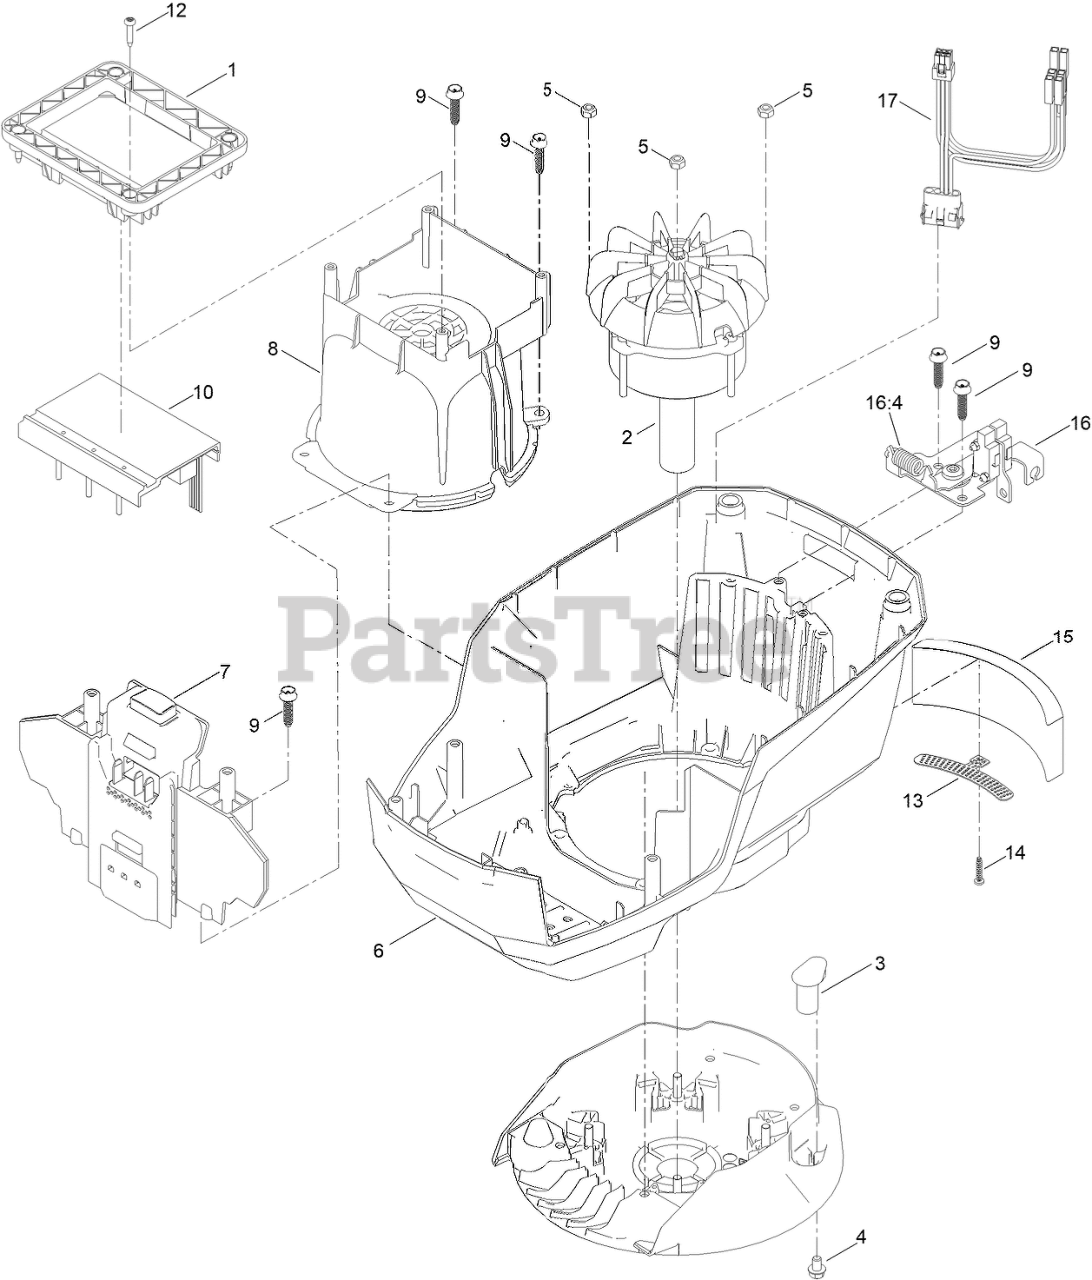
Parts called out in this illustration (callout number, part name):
1	BASE-MOUNT, MOTOR
2	MOTOR, 60 VOLT
3	INSERT-MOUNT, Motor
5	NUT-LOCK
6	SHROUD-LOWER
7	BATTERY RECIEVER ASM
8	SHROUD-MOTOR
9	SCREW-FLANGE, PLASTIC
10	CONTROLLER-MOTOR, 60 VOLT
13	BRACKET-FOAM
14	SCREW-PLASTIC, PPH
16	BAIL SWITCH ASM
16:4	SPRING-EXTENSION
17	HARNESS-WIRE
